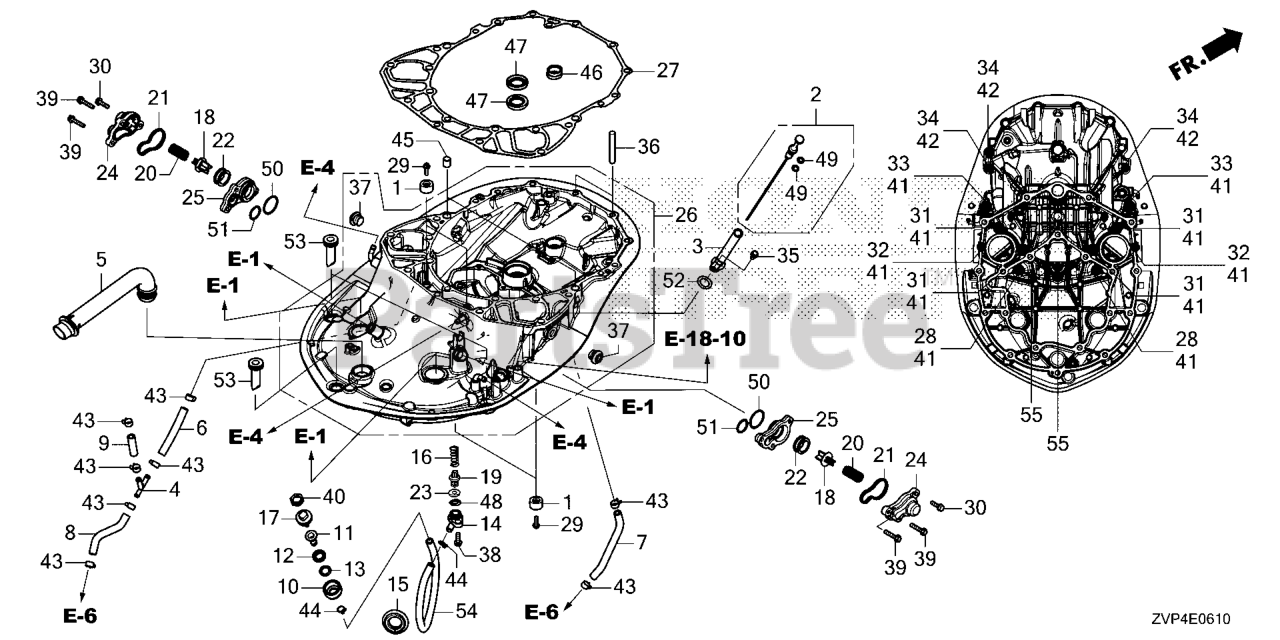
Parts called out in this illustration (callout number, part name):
1	METAL, ANODE
2	GAUGE COMP
3	PIPE COMP, OIL LEVEL
4	JOINT, FUEL TUBE
5	PORT, IDLE EX.
6	TUBE, FLUSH VALVE
10	NUT, WATER MOUTH
11	JOINT, WATER HOSE
12	SEAT, WATER MOUTH
13	SEAT, WATER JOINT
14	COVER, FLUSH VLV
15	GROMMET, WATER TUBE
16	SPRING, FLUSH VALVE
17	CAP, WATER JOINT
18	VALVE, RELIEF
19	VALVE, FLUSH
20	SPRING, RELIEF VALVE
22	GASKET, RELIEF VALVE
23	PKG, FLUSH VALVE
24	COVER, L. RELIEF VALVE
25	SPACER, L. RELIEF VALVE *TGRAY* (GRAY)
26	CASE COMP, MOUNT
27	GSKT, MOUNT CASE
28	BOLT, HEX. (12X100)
29	BOLT, FLANGE (6X18)
30	BOLT, FLANGE (6X23) Use from Frame SN 4800343.
31	BOLT, HEX. (12X175)
32	BOLT, HEX. (12X55)
33	BOLT, HEX. (12X65)
34	BOLT, HEX. (10X60)
35	BOLT, FLANGE (6X14)
36	BOLT 2, STUD (10X50)
37	BOLT, SEALING (18MM)
38	BOLT, FLANGE (6X20) (ENGINE NO.)
39	BOLT-WASHER (6X35)
40	NUT, HEX. (16MM) DUAL QTY = (2) (SINGLE)
41	WASHER, PLAIN (12MM)
42	WASHER, PLAIN (10MM)
43	CLAMP D12.5, TUBE
44	CLIP B1, TUBE
45	PIN, DOWEL (14X15)
46	BEARING, NEEDLE (20X28X13) (SOLID)
47	OIL SEAL (25X40X7)
48	O-RING (16MM)
49	O-RING (8.8X1.9)
50	O-RING (33.5X2)
51	O-RING (23.5X2)
52	O-RING (15.5X3.5)
53	GROMMET (1WAY)
54	BULK HOSE, FUEL (8X1000) (95001-80001-(95001-80001-60M)
55	BOLT (10X80)
